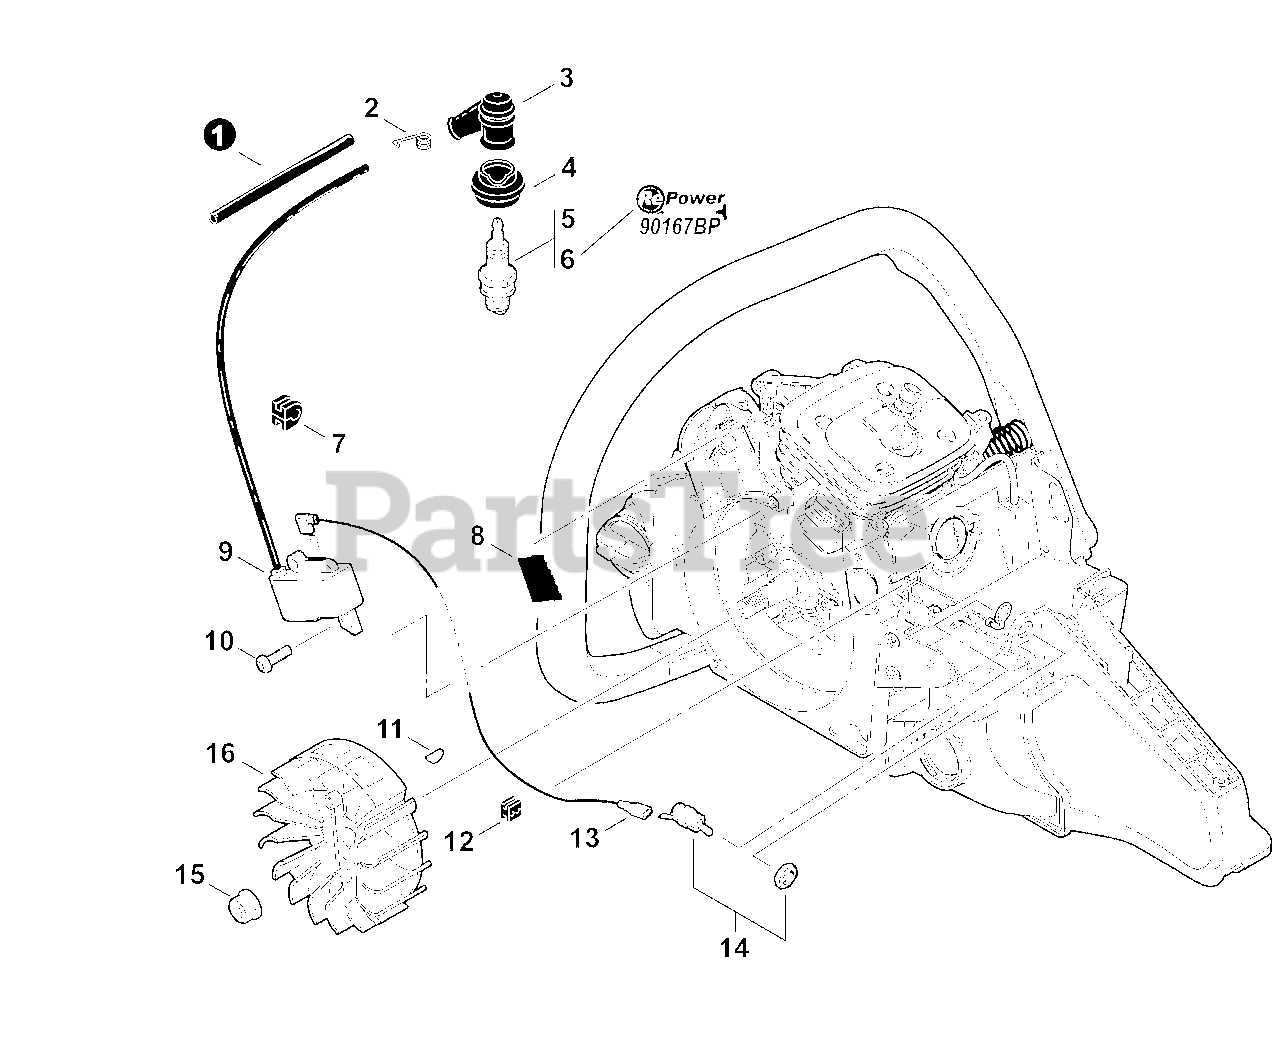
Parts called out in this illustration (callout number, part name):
2	TERMINAL, SPARK PLUG CAP
3	CAP, SPARK PLUG
4	SEAL, SPARK PLUG
5	SPARK PLUG -- BPM-8Y
6	SPARK PLUG -- BPMR-8Y CANADA
8	CUSHION
9	COIL, IGNITION
10	SCREW - 5×16
11	KEY, WOODRUFF
13	LEAD - IGNITION
14	IGNITION SWITCH KIT
15	NUT - 8 -- FLANGE
16	FLYWHEEL
